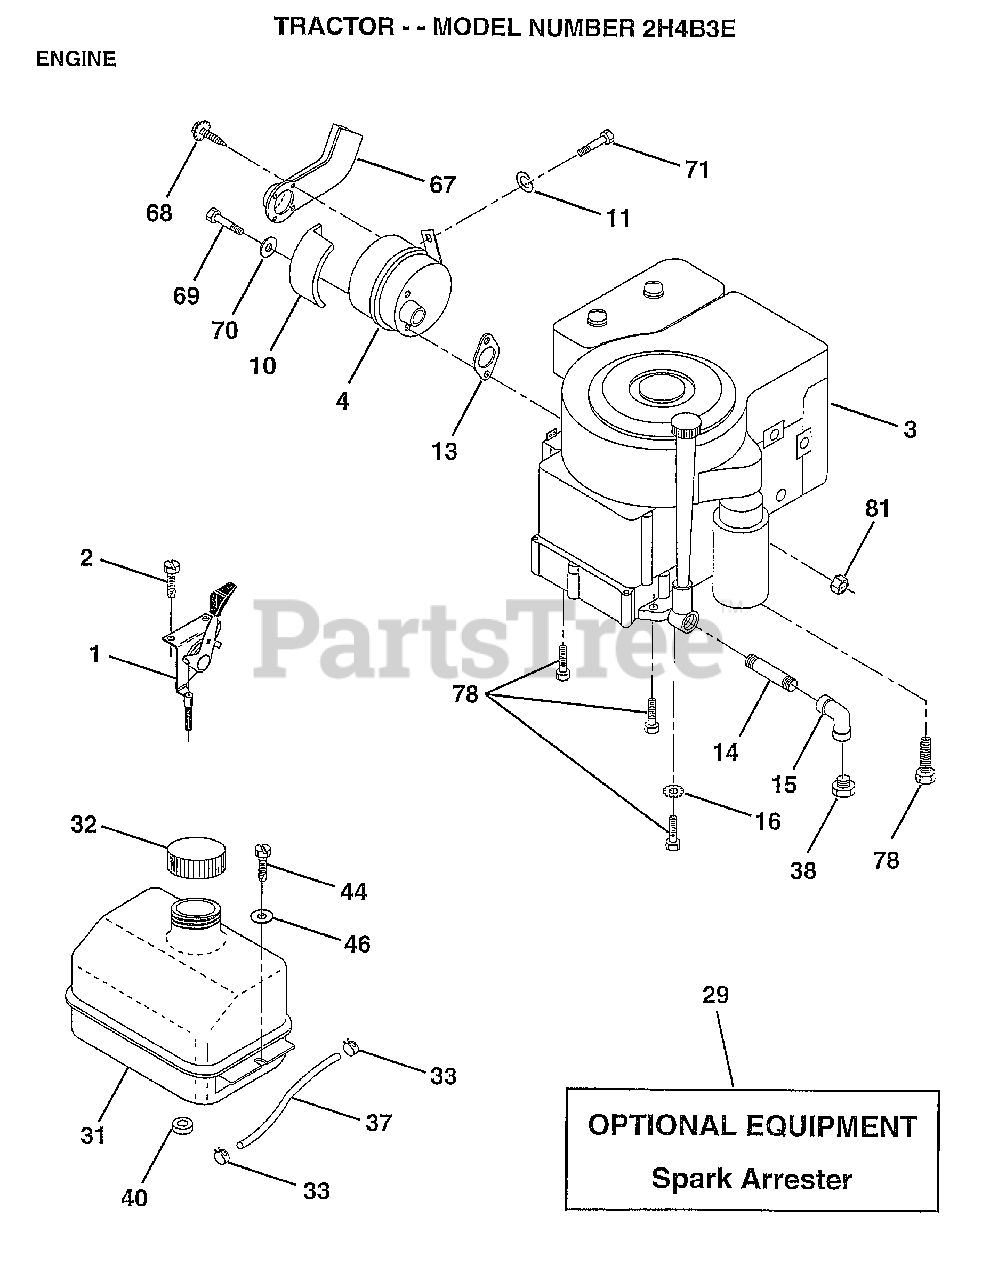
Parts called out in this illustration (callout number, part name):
1	THROTTLE CONTROL
2	SCREW LT
4	MUFFLER LTV
10	SHIELD HEAT LTV
11	LOCKWASHER
13	GASKET ENG 1 313 LD TIN PLATED
14	PIPE NIPPLE
15	ELBOW
16	LOCKWASHER
31	TANK.FUEL.LT.
32	CAP ASM FUEL
33	HOSE CLAMP
37	LINE FUEL
44	SCREW HEX CRT
46	WASHER
67	DEFLECTOR MUFFLER
69	"BOLT,HEX"
70	WASHER T
71	BOLT HXHD FIN
78	SCREW
81	NUT
